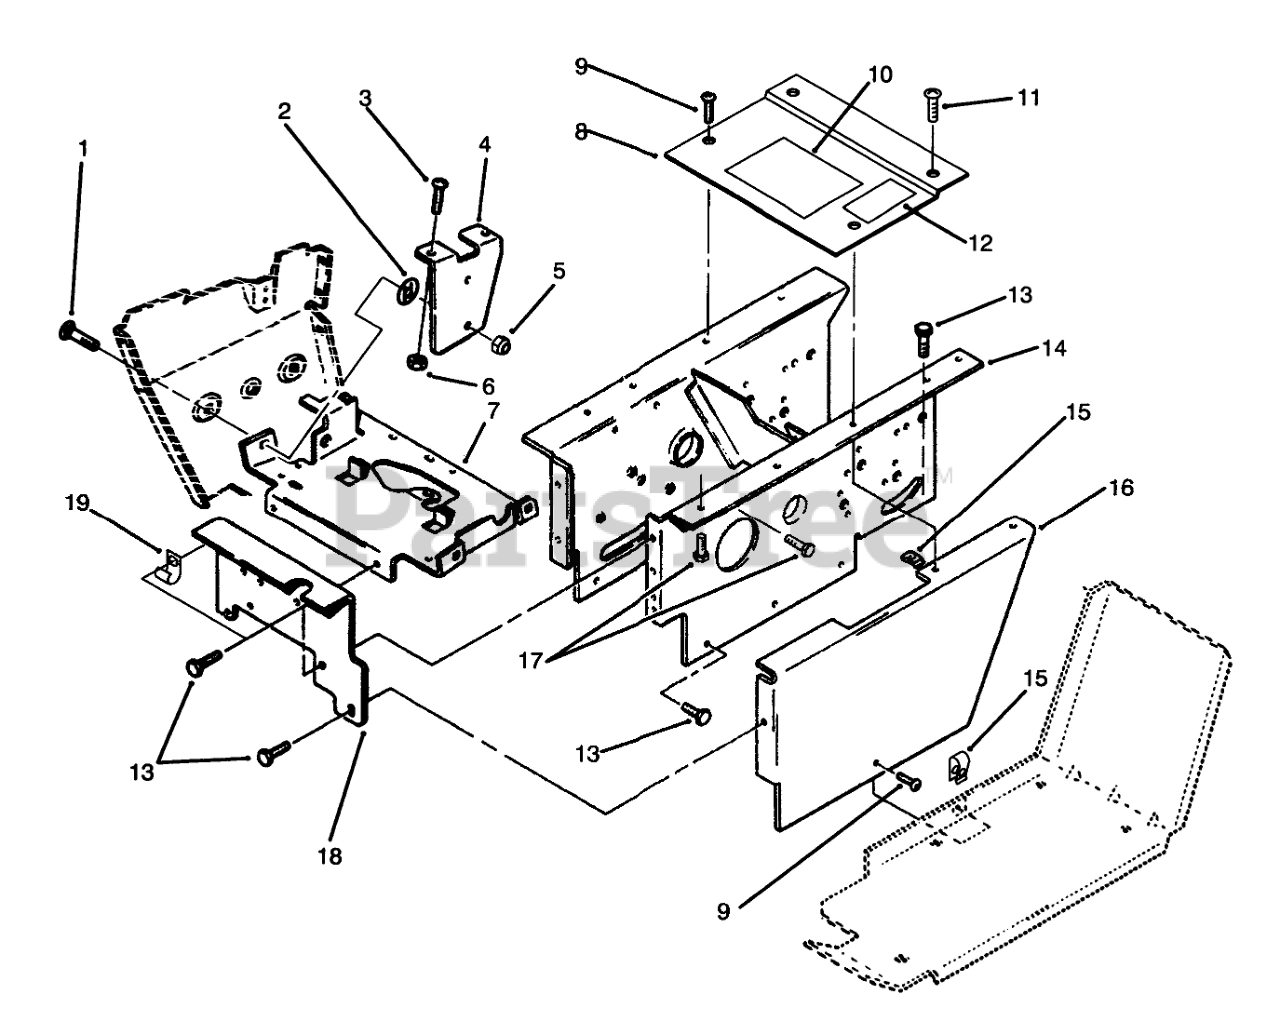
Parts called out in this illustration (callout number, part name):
1	BOLT-CARR
2	NUT-PUSH
3	SCREW-HH
4	Bracket-Holder
5	NUT-LOCK, NI
6	Nut
7	WLD-SUPPORTB
8	Plate-Hoodstand, Top (Incl. Ref.#10)
9	Screw
10	DECAL-DANGER
11	Screw
12	DECAL-PARKING BRAKE
13	SCREW
14	Hoodstand
16	Cover-Side LH
17	SCREW-HH
18	Plate-Front
19	CLIP
